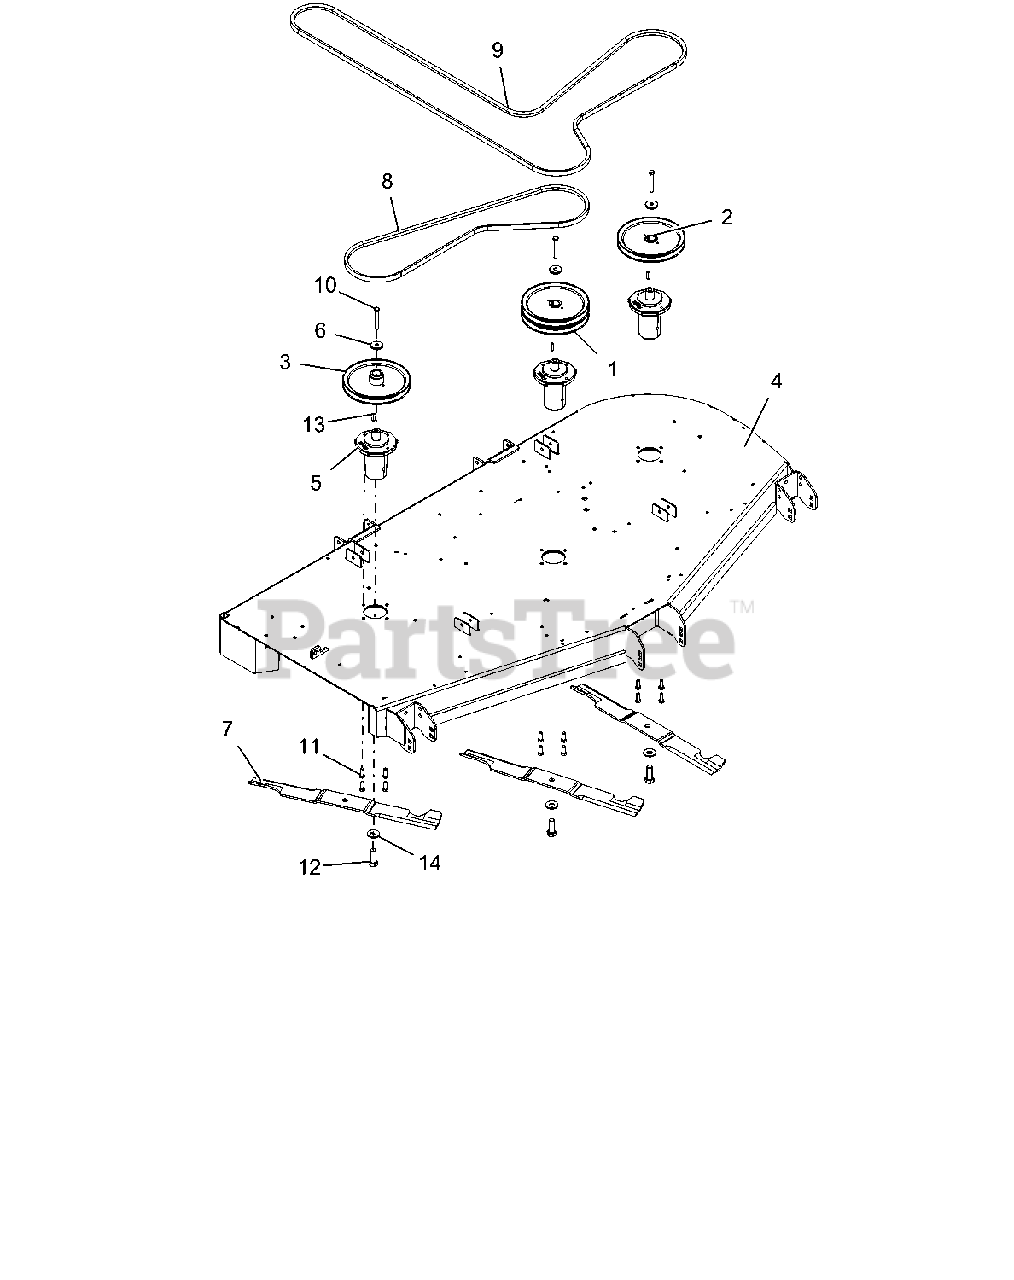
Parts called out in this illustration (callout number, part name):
1	SHEAVE-DOUBLE 1.00"IDX8.25"OD
2	SHEAVE-SINGLE 1.00"IDX8.25"OD
3	SHV-SINGLE 1.00"ID X 8.25"OD
4	72"SIDE DISCH DECK WMT W/SAFE
5	ASM, MAINT FREE SPINDLE
6	RETAINER, SHEAVE
7	BLADE, 72"
8	V-BELT, B-COGGED
9	V-BELT, HB WRAPPED
10	BLT-HEX .38-16X2.75 GR8 YWZC
11	BLT-HEX .38-16X1.0 GR8 YZ EP30
12	BLT-HEX .62-18X1.75 GR8 YWZC
13	KEY, SQ .25X.25X1.00 RC 40-50
14	WSHR-BLVL .669X1.535X.138
